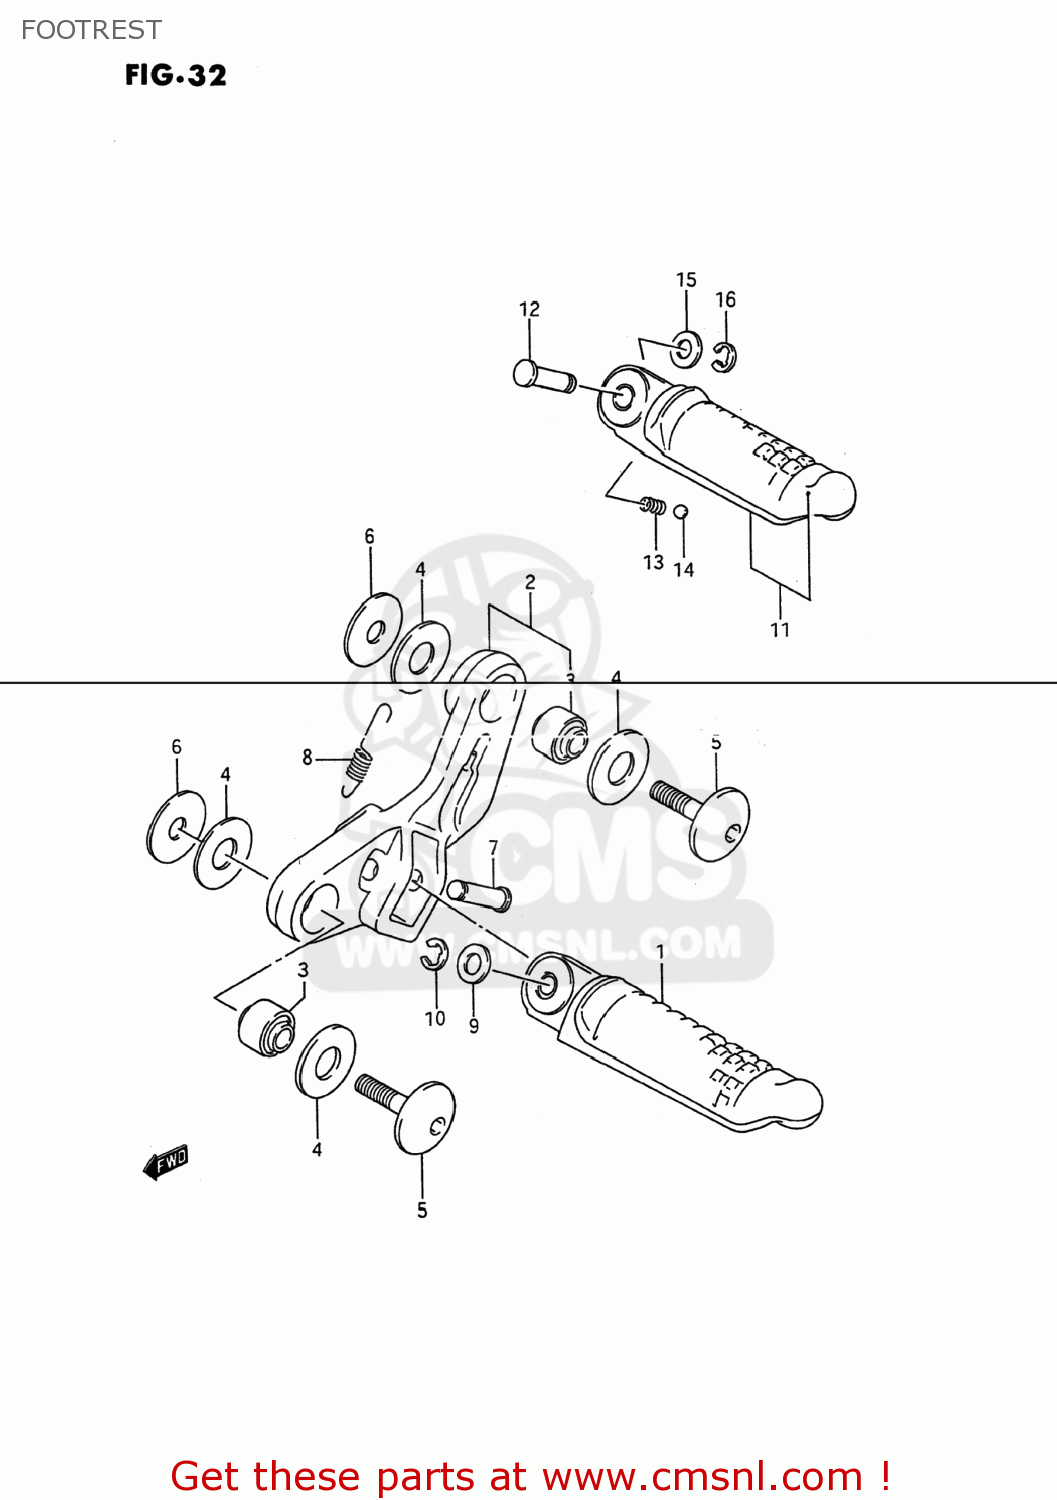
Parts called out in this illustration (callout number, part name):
1	BAR,FRONT FOOTREST,LEFT
2	HOLDER,FR FOOTREST,R
3	BUSH(8.4X20X18)
4	WASHER(12.5X30X2)
5	BOLT(8X31)
6	WASHER(8.5X30X2.3)
7	PIN(8X33.2)
8	SPRING
9	WASHER
10	E RING
11	BAR,PILLION FOOTREST,R
12	PIN
13	SPRING
14	BALL
15	WASHER
16	E.RING
